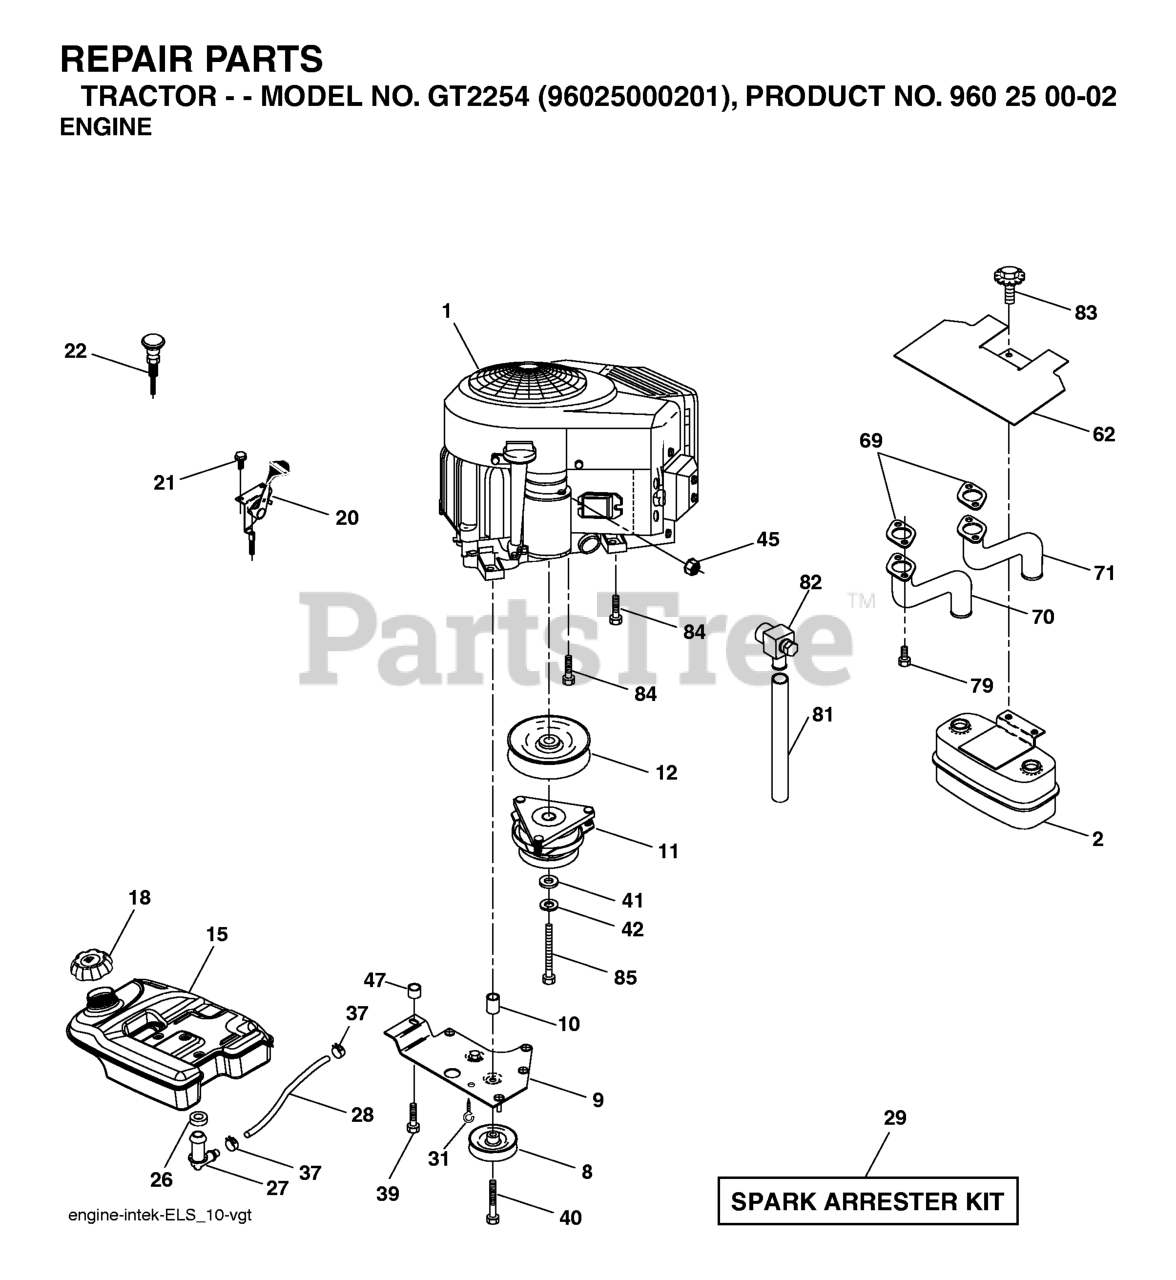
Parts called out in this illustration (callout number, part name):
2	MUFFLER.TWIN.CYL.LOW.TONE
8	RP.IDLER GROOVED
9	KEEPER ASM BELT ENGINE
11	CLUTCH MZ ZTR GT.48/54"1.125"
12	PULLEY ENG VGT ELECT CLUTCH
15	TANK.FUEL.5.0 LEFT.FILL.YTGT
18	TANK CAP
20	THROTTLE CABLE
21	SCREW
22	CONTROL.CHOKE.ERGO.PUSH-IN.BLA
26	BUSHING OUTLET T
27	STEM FUEL TANK
28	LINE.FUEL.35.25"
29	KIT.SPARK ARRESTOR 794945 B&S
37	HOSE CLAMP
39	SCREW TT 3/8-16X2-1/4 UNC
40	Screw TT 3/8-16 x 4 unc
42	LOCKWASHER
45	NUT
62	RP SHIELD HEAT MUFFLER
69	GASKET.MUFFLER
70	TUBE.EXHAUST.B&S.VGT.LH
71	TUBE.EXHAUST.B&S.VGT.RH
79	SCREW.SOCKET.HEAD.5/16-18
81	TUBE, DRAIN, OIL
83	BOLT.5/16-18UNCX3/4 W/SEMS.BLK
84	SCREW 3/8-16 X 1-1/2
85	BOLT HEX 7/16-20 X 3.75 GR. 5
